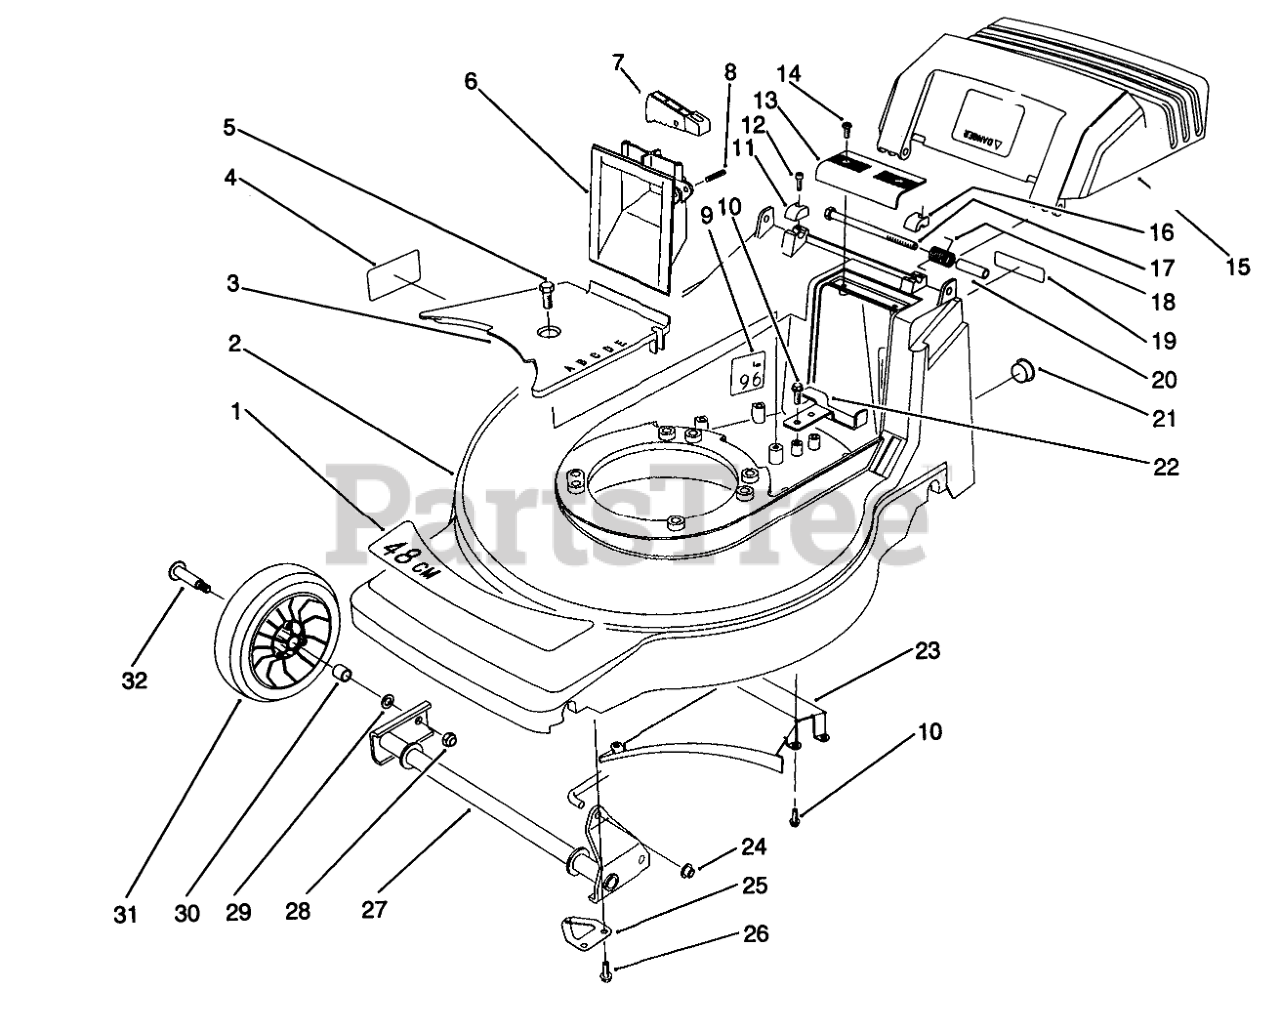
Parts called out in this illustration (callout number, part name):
1	DECAL - DECK
2	Housing-48cm
3	BELT COVER
4	Decal Danger
5	SCREW-HWHTF
6	GRIP - LOWER
7	TRIGGER - HOC
8	PIN-SPIRAL
9	Decal-Noise
10	SCREW-HWHTF
11	CAP-HINGE BOLT, RH
12	SCREW-HSH
13	GRIP-UPPER
14	SCREW-PPH, PLASTITE
15	Door-Discharge
16	CAP-HINGE BOLT, LH
17	SCREW-HH
18	DOOR SPRING
19	DECAL FRENCH REGUL.
20	SPACER-DOOR
21	DOME PLUG (DP-1000)
22	REAR BELT GUIDE
23	Ramp-Discharge
24	NUT-PUSH
25	SHAFT RETAINER ASM
26	Screw
27	FRONT PIVOT WA
28	NUT-HEX
29	WASHER
30	BUSHING
31	Wheel & Tire Assembly (Incl. Ref. #30)
32	BOLT-WHEEL
